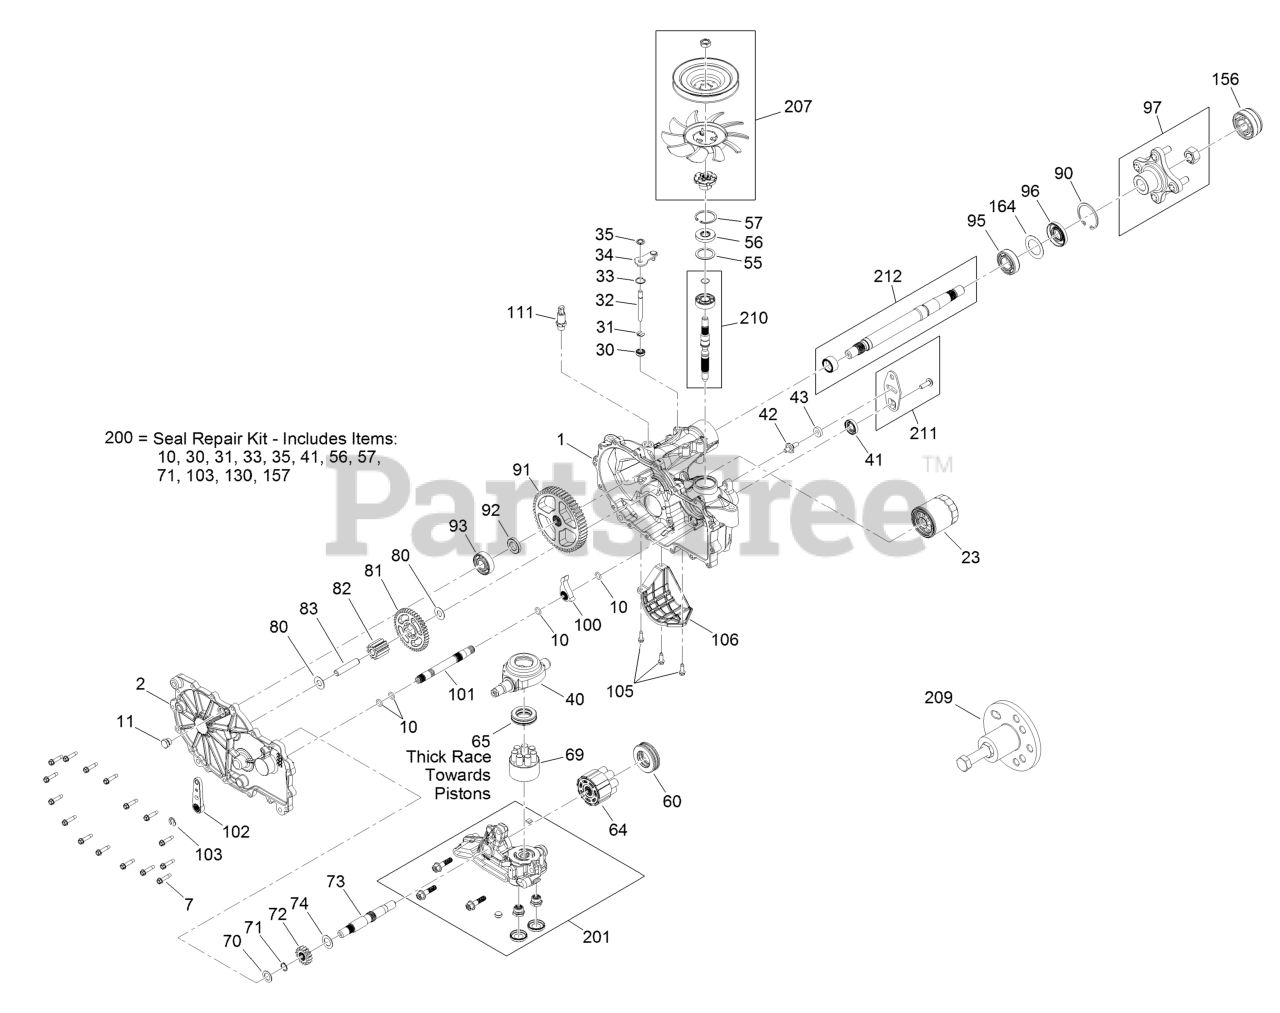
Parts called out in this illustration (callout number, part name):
1	Main Housing Kit
2	LH Side Cover Kit
7	Screw-HHF
11	Plug-Straight
23	Element-Oil Filter, HYD
30	Seal-Lip
31	Ring-Retaining, External
32	Rod-Bypass
33	Ring-Retaining, Internal
34	Arm-Bypass
35	Ring-Retaining, External
40	Swashplate-Trunnion
41	Seal-Lip
43	Puck-Friction
56	Seal-Lip
57	Ring-Retaining
60	Bearing-Thrust
64	Motor Cylinder Block Kit
65	Bearing-Thrust
69	Pump Block ASM
70	Washer-Flat
71	Ring-Retaining
72	Gear-16T
73	Shaft-Motor
80	Washer
81	Gear-43T
82	Gear-11T
83	Pin-Jackshaft
90	Ring-Retaining
91	Gear-54T
93	Bearing Kit
95	Input Bearing Kit
96	Seal-Lip
97	Hub Kit
100	Pawl-Brake
101	Shaft-Brake, Inboard
102	Handle-Brake
103	Ring-Retaining, EXT
106	Guard-Filter, LH
111	Adapter-Straight
156	Cover-Nut, Axle
200	Seal Kit
201	Center Section Kit
207	Fan Pulley Kit
209	Puller-Hub, 4 Bolt
210	Input Shaft Kit
211	Control Arm Kit
212	Axle Shaft Kit
